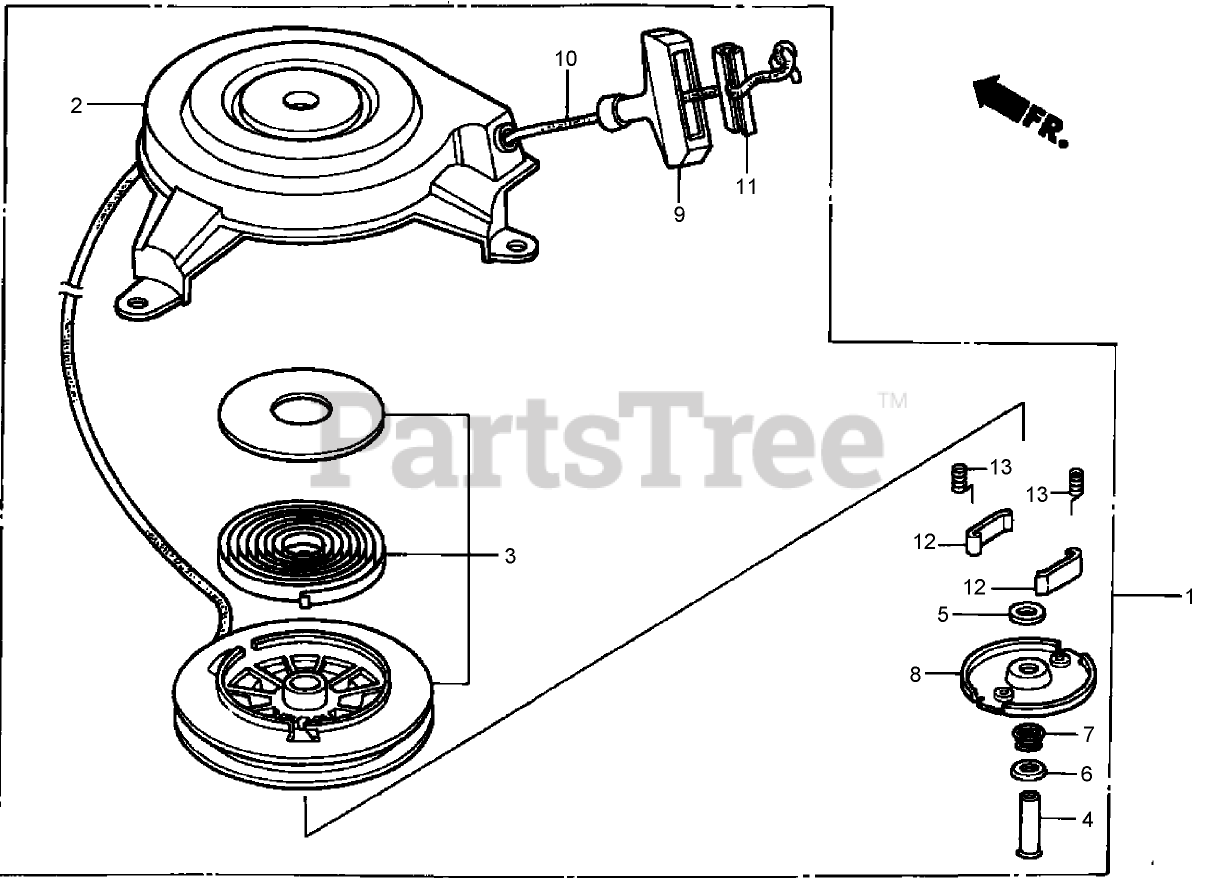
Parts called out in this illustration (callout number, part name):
1	RECOIL STARTER ASM
2	HOUSING ASM
3	PULLEY AND SPRING ASM
4	Pin-Center
5	Plate A-Friction
6	PLATE B-FRICTION
7	Spring-Friction
8	Retainer
9	Handle
10	ROPE-STARTER, RECOIL
11	Handle-Reinforcement
12	Ratchet-Starter
13	Spring-Dog
